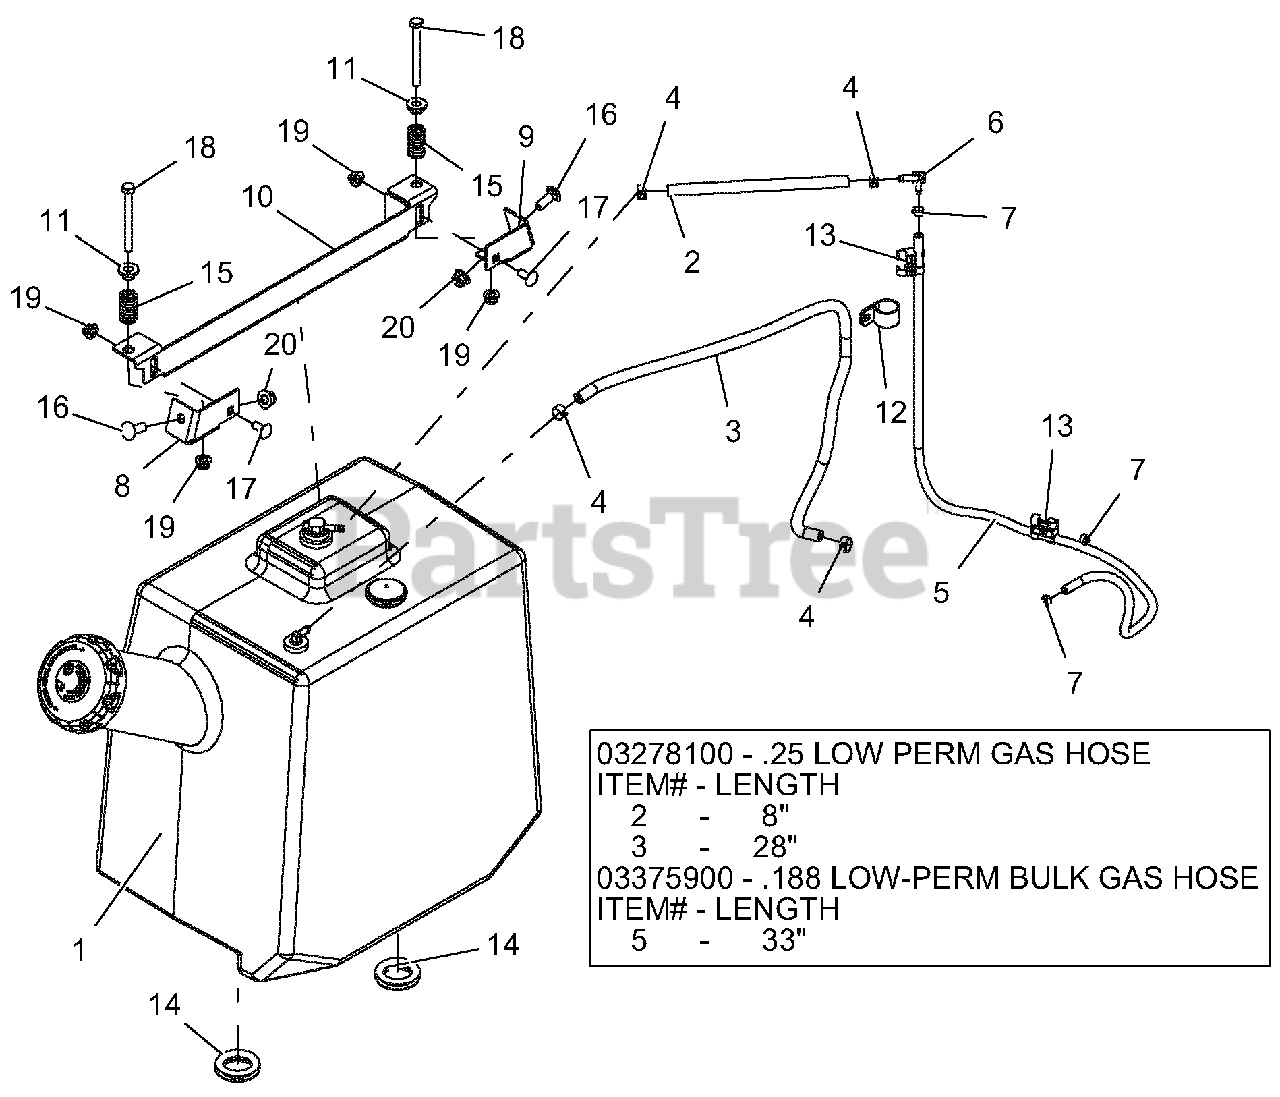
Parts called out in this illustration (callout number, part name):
1	ASSY, EPA PROSTANCE FUEL TANK
2	.25 LOW PERM GAS HOSE
3	.25 LOW PERM GAS HOSE
4	CLAMP, FUEL LINE
5	HOSE, .188 LOW-PERM BULK GAS
6	FITTING-3/16X1/4 90DEGREE VAC
7	CLAMP - HOSE, SPRING .188
8	WLDMT, TANK HOLDDOWN-RH
9	WLDMT, TANK HOLDDOWN-LH
10	HOLDDOWN, FUEL TANK
11	BSHG, FLG .385 X .500 X .875 X .406
12	CLAMP, CUSHIONED STEEL REV
13	CLIP, T, .38-.50
14	GROMMET, 1.25"
15	SPRG, COMPRESSION
16	BLT-RDHDSQNK .38-16X1.00 G5 YWZC
17	BLT-RDHDSQNK .31-18X.75 G5 YWZC
18	BLT-HEX .31-18X3.25 GR5 YWZC
19	NUT-LK-NYL-FLG .31-18 YWZC
20	NUT-LK-NYL-FLG .38-16 YWZC
